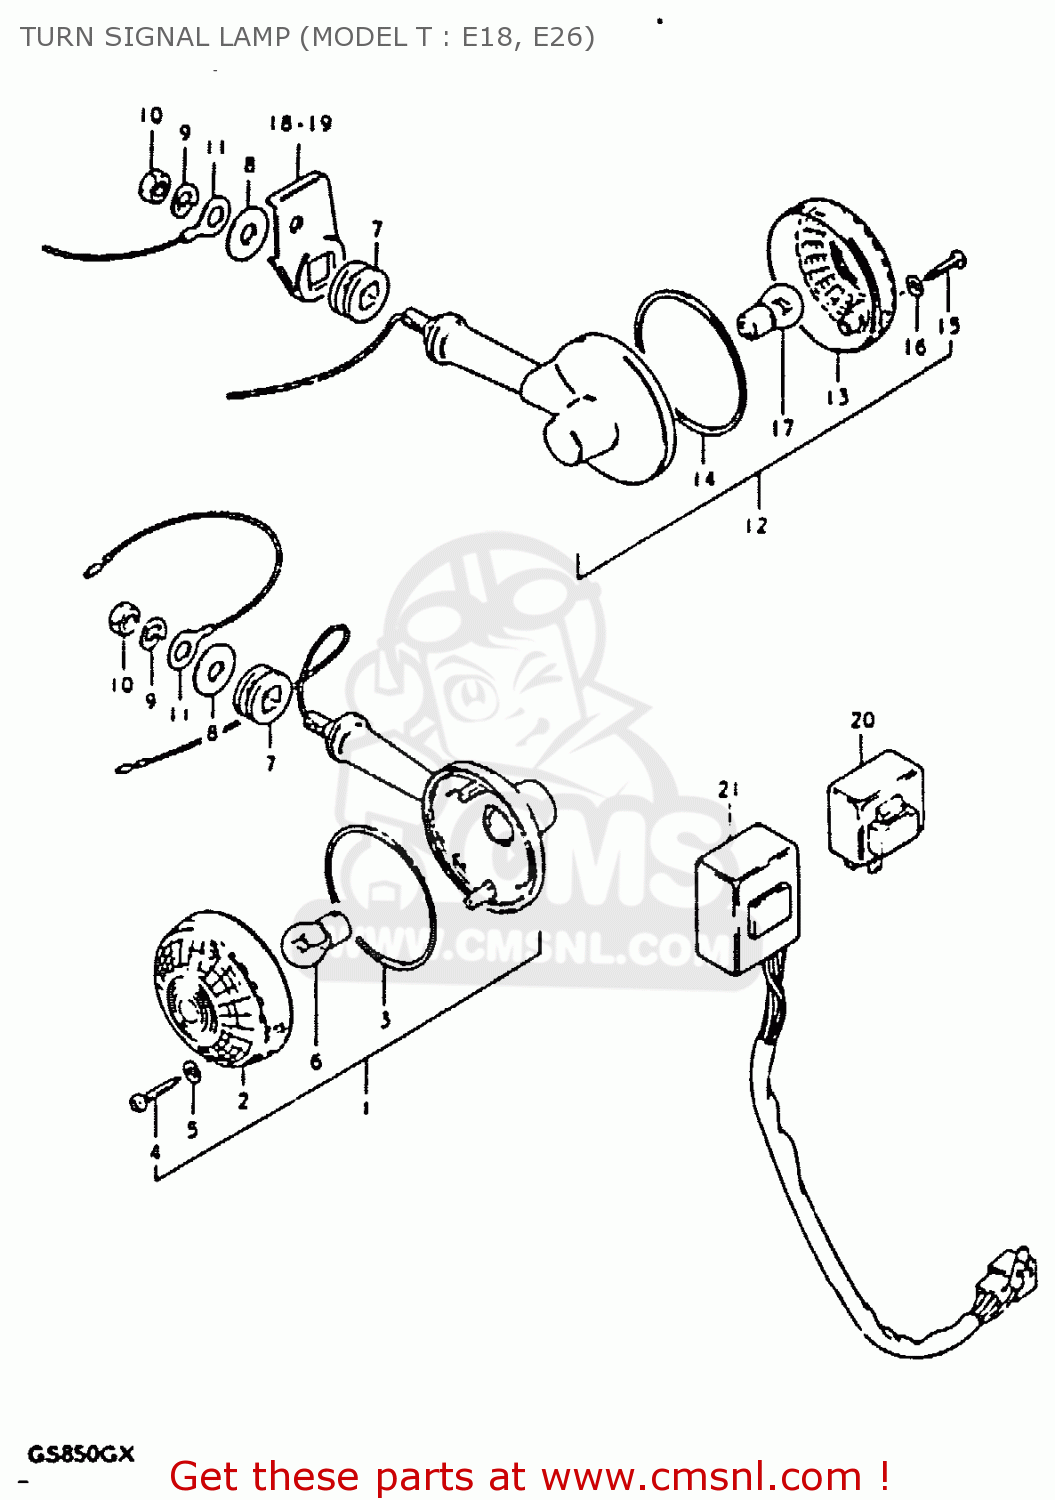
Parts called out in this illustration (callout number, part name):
1	LAMP, REAR TURN SIGNAL
2	LENS
3	GASKET (NAS)
4	SCREW (4X30)
5	GASKET (NAS)
6	BULB(12V21W)
7	CUSHION
8	WASHER (10.5X30X2.3)
9	LOCK WASHER
10	NUT
11	LEAD WIRE,EARTH
12	LAMP, REAR TURN SIGNAL
13	LENS
14	GASKET (NAS)
15	SCREW (4X30)
16	GASKET (NAS)
17	BULB(12V21W)
18	BRACKET,RR TURNSIGNAL LAMP,R
19	BRACKET,RR TURNSIGNAL LAMP,L
20	RELAY,TURN SIGNAL
21	UNIT,TURN SIGNAL CONTROL
